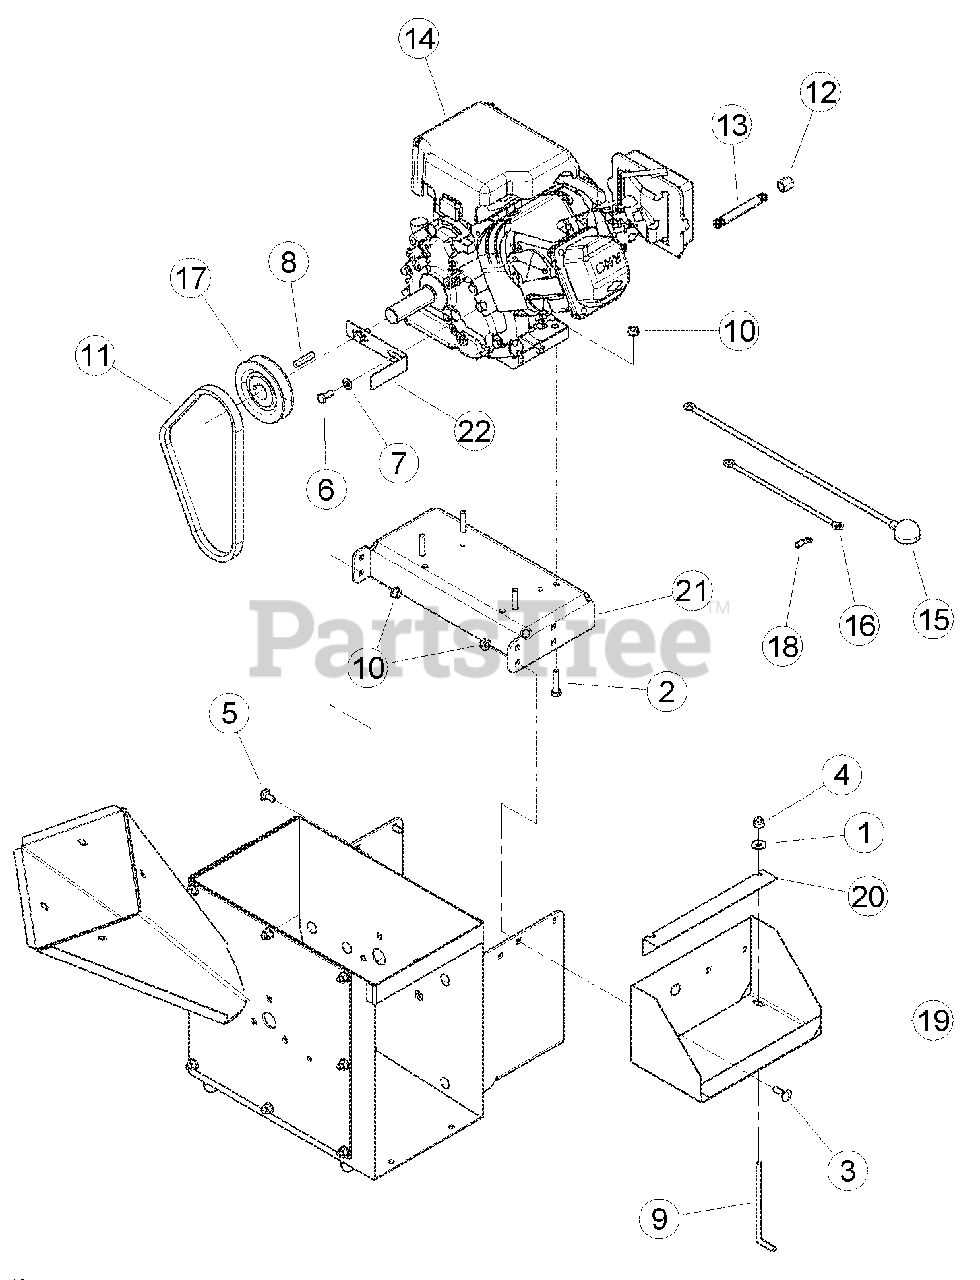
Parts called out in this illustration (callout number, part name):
1	WASHER, 5/16 FLAT ZP (SC3305E ONLY)
2	BOLT, 5/16 X 1_1/2 HEX HD GR5 ZP
3	BOLT, 5/16 X 1 GR5 CRG ZP (SC3305E ONLY)
4	NUT, 5/16 NE NYLOCK ZP (SC3305E ONLY)
5	BOLT, 5/16 X 3/4 CRG GR5 NC ZP
6	BOLT, 5/16-24 X 3/4 HEX HD GR5 ZP
7	WASHER, 5/16 SAE FLAT ZP
8	KEY, 1/4 SQUARE X 1-1/2 LONG PLAIN
9	BOLT, 5/16 X 8-3/4 L-TYP BATTERY (SC3305E ONLY)
10	NUT, 5/16 FLANGE TOPLOCK
11	BELT, 29" C/S
12	PIPE CAP, 1/4" GALV. HEX HEAD
13	PIPE NIPPLE, 1/4 X 4 GALVANIZED
14	ENGINE,CHP-SHD 305CC BRIGGS ELEC (FOR SERVICE SEE ENGINE OWNERS MANUAL OR YOUR NEAREST BRIGGS & STRATTON ENGINE DEALER)
14	ENGINE, 900 SERIES B+S HORIZONTAL (FOR SERVICE SEE ENGINE OWNERS MANUAL OR YOUR NEAREST BRIGGS & STRATTON ENGINE DEALER)
14	ENGINE, 305CC B+S HORIZONTAL (FOR SERVICE SEE ENGINE OWNERS MANUAL OR YOUR NEAREST BRIGGS & STRATTON ENGINE DEALER)
15	CABLE, 33" POS R/R WITH BOOT (SC3305E ONLY)
16	CABLE, 9" NEG R/R (SC3305E ONLY)
17	PULLEY, CAST 4" OD,1"BORE,B GRV
17	PULLEY, CAST 4"OD,3/4"BORE,B GR (SC3206 ONLY)
18	TERMINAL, 14/16 GA ELECTRICAL (SC3305E ONLY)
19	WELDMENT, BATTERY BOX (SC3305E ONLY)
20	ANGLE, BATTERY HOLD DOWN (SC3305E ONLY)
21	PLATE, ENGINE MOUNTING
22	GUIDE, BELT
